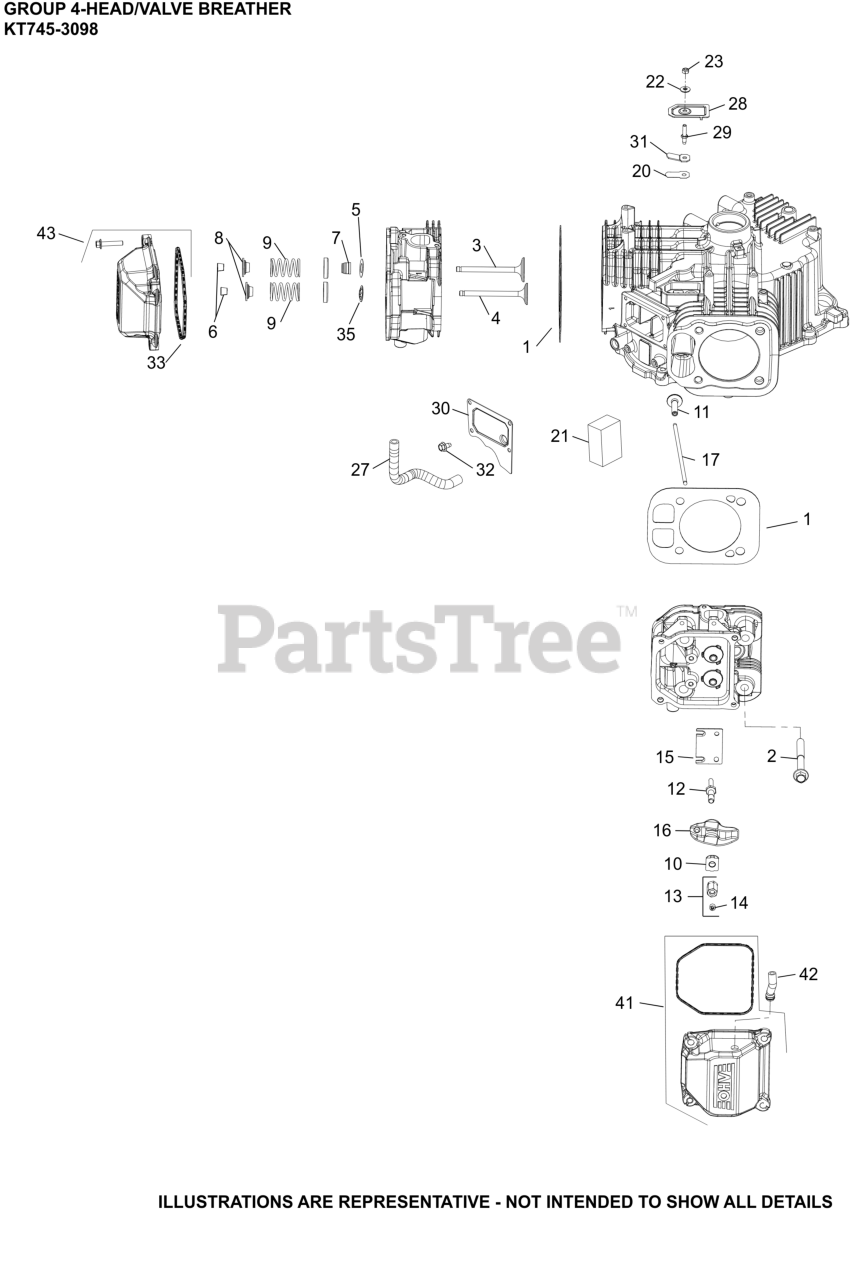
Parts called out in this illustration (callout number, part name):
1	KIT, CYLINDER HEAD GASKET
2	SCREW, HEX FLANGE M10 X 1.5-6g X 90mm
3	VALVE, INTAKE
3	VALVE, INTAKE (.25) - (#2401702S)
4	VALVE, EXHAUST
4	VALVE, EXHAUST (.25)
5	SPACER (.010")
6	KIT, RETAINER
7	SEAL, VALVE BAND
8	CAP, VALVE SPRING
9	SPRING VALVE
10	PIVOT, ROCKER ARM
12	STUD, ROCKER
13	HEX NUT ASSEMBLY
14	SCREW, SET
15	PLATE, GUIDE
16	ARM, ROCKER
17	ROD, PUSH
20	REED, BREATHER
21	FILTER, BREATHER
22	WASHER, SEALING
23	NUT, LOCK M5X.8
27	HOSE, BREATHER
28	COVER, BREATHER REED
30	COVER, BREATHER MEDIA
31	RETAINER, REED
32	SCREW, THREAD FORMING
33	O-RING (YELLOW), VALVE CO
35	RETAINER, VALVE GUIDE (KM)
41	KIT,BREATHER VALVE COVER (PLASTIC)
42	HOSE, FP-USE 32 326 07-S(PLASTIC COVERS)
43	KIT, VALVE COVER-PLAIN (PLASTIC)
NI	SCREW, HEX FLANGE (M6 X 31.625 DOG PT)
NI	KIT, #1 CYLINDER HEAD
NI	KIT, #2 CYLINDER HEAD
